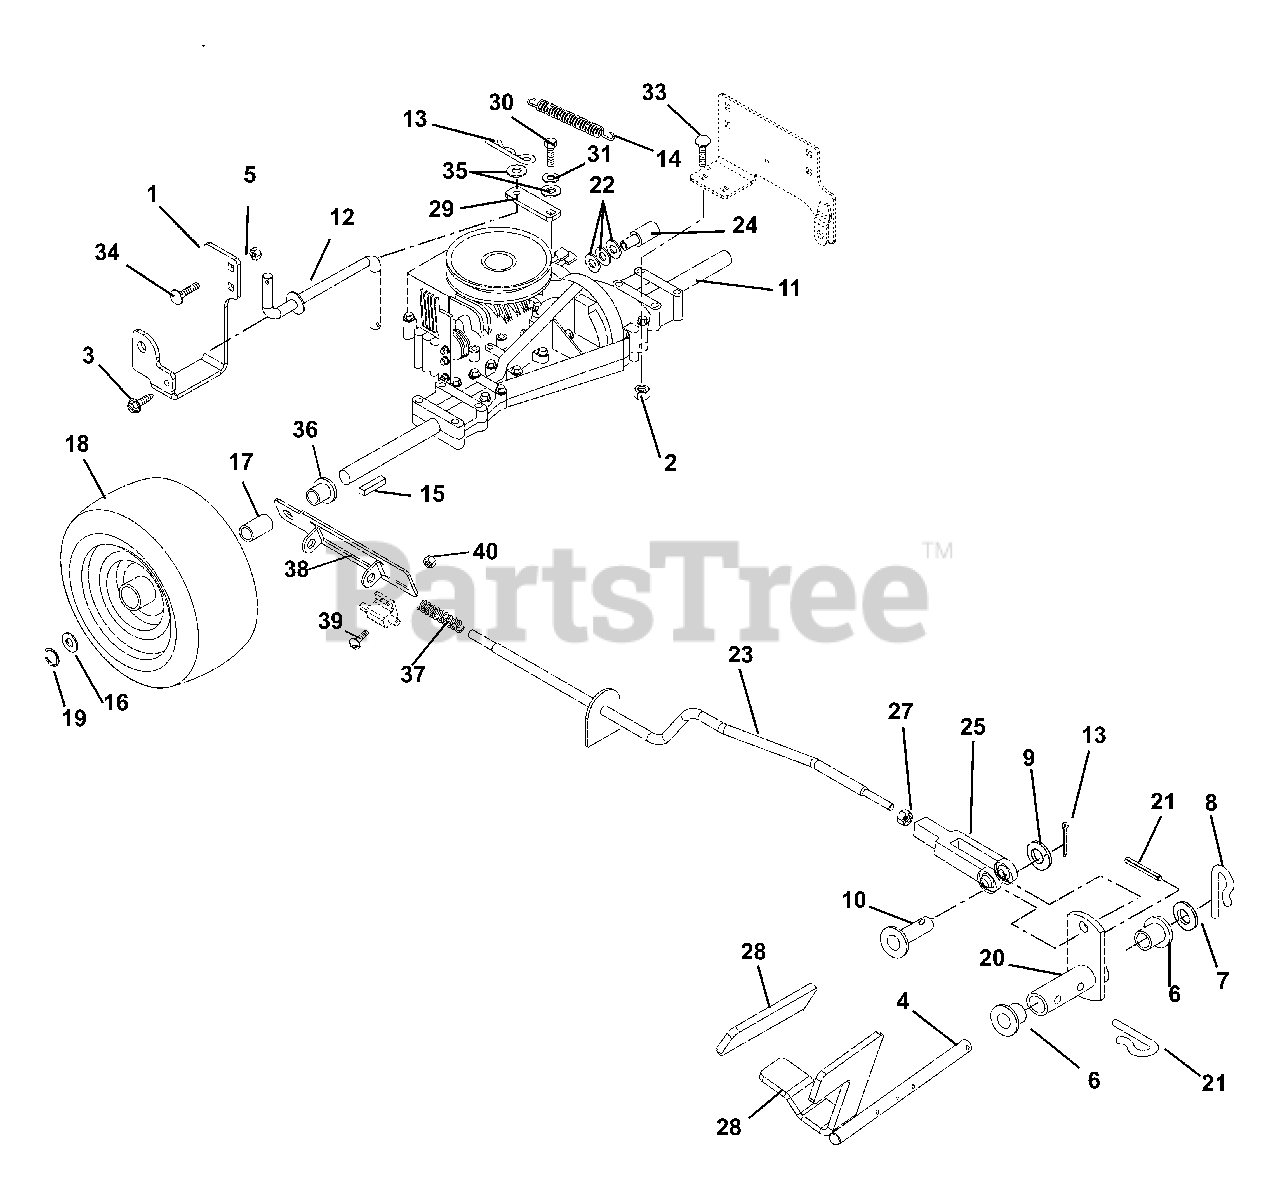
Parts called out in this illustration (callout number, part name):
1	Support, Transmission
2	Nut, Flange .50-13
3	Screw-Tapping .31-18 x .75 Hex Washer Head
4	Weldment, NMIR Shift Pedal
5	Nut, Locking Top Flange .38-16
6	Bushing, Flange .515 x .75 x .745 x 1.00
7	Washer, Flat Steel .505 x 1.00 x .062
8	Clip, Spring
9	Washer, Flat Steel .38 x .87 x .179
10	Pin, Clevis .31 x .822
11	Transmission Peerless Hydro
12	Rod, Transmission Disconnect
13	Pin, Hair
14	Spring, Tension .043 x .44 x 3.31
15	Key, Square .188 x 2.0 x .188
16	Washer, Flat Steel .755 x 1.25 x .125
17	Spacer, Wheel .75 x 1.00 x 1.25
18	Assembly, Tire and Wheel 16 x 6.5 x 8 (066, 068)
18	Tire 16 x 6.50-8 2 Pulley
19	Ring, Retaining External .75 x .05
20	Weldment, Shift Rod and Hub
21	Pin, Center .12 x 1.00 Extended Prong Square Cut
22	Washer, Flat, Steel .50 x 1.00 x .062
23	Rod, NMIR Shift
24	Trunnion
25	Yoke .31-24 x 2.250
26	Washer, Flat Steel .390 x .750 x .125
27	Nut-Locking-Nylon .375-24 With Insert
28	Grip, Pedal
29	Tab, Transmission Disconnect
30	Bolt-Hex .25-28 x .75 Grade 5
31	Washer, Locking .25 x .062 Regular
32	Washer, Flat Steel .328 x 1.00 x .094
33	Bolt, Round Head Square Neck .31-18 x 2.50 Grade 5
34	Bolt, Round Head Square Neck .38-16 x .75 Grade 5
35	Washer, Flat Steel .38 x .875 x .083
36	Bushing, Flange .406 x .88 x .270 x .140
37	Spring, Commpression .081 x .720 x 2.75
38	Bracket, NMIR Shift
39	Screw, Machine 10-24 x .75 HWH
40	Nut-Locking-Nylon 10-24 With Insert
